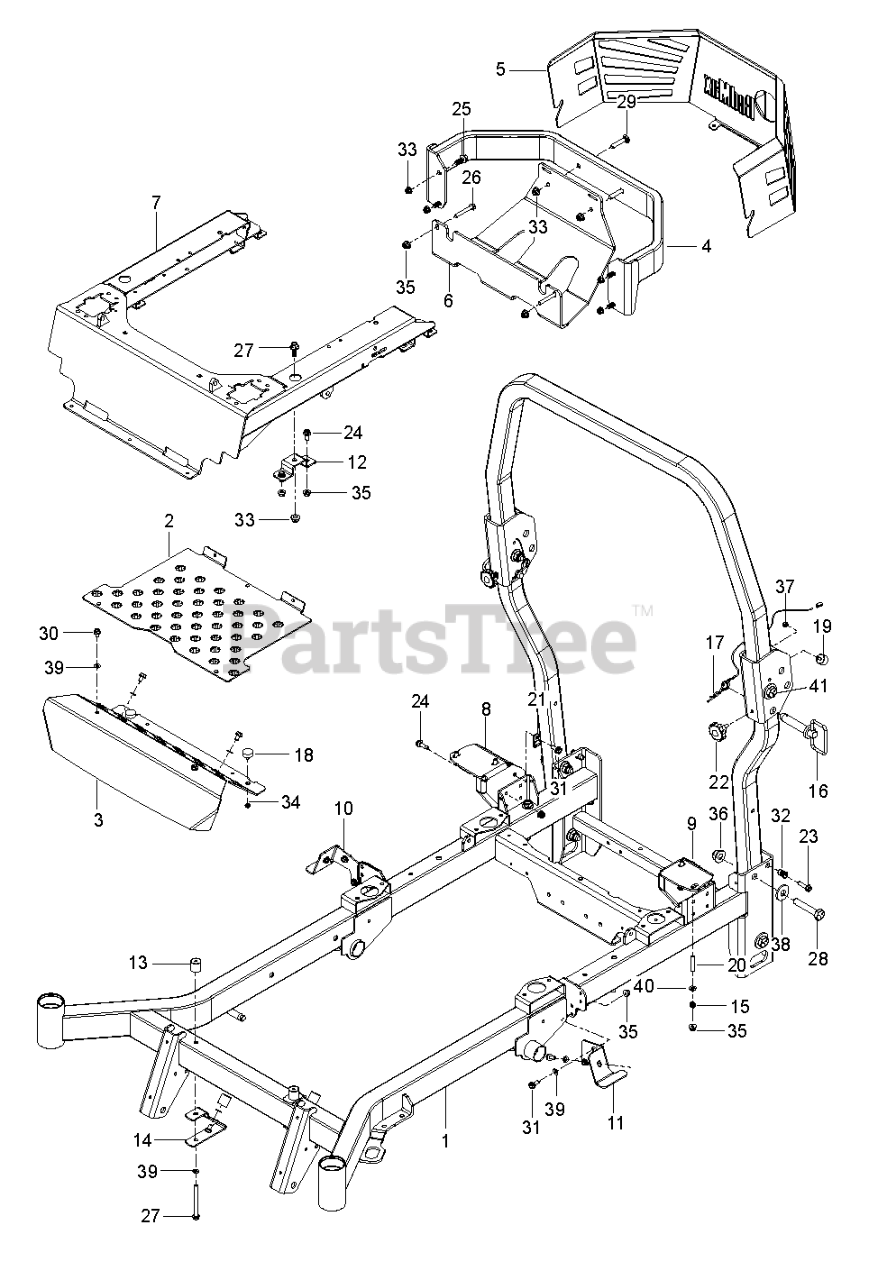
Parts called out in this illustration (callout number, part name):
1	FRAME.W/DECALS/CZT/REDMAX.672
2	PLATE FLOOR PAN SNAPPER RED X6
3	PLATE.FOOT.REST.BLACK
4	BUMPER REAR LONG SNAPPER RED X
5	GUARD REAR SNAPPER RED X672
6	PLATE, SKID, BLACK
7	FRAME SEAT MOUNT SNAPPER RED X
8	MOUNT, RT TANK, BLK
9	MOUNT, LT TANK, BLK
10	BRACKET TANK.FT.RT BLACK MS-43
11	MOUNT, TANK, LT-BLK
12	MOUNT MID-SECTION BLACK MS-431
13	MOUNT, F/F INSERT
14	BRACKET, REST MOUNT
16	PIN.ROPS.W/HANDLE
17	PIN.HAIR.DOUBLE.LOOP.W/LANYARD
18	BUMPER, 1/4-20 STUD, 1/4
19	BUMPER, MALE STUD, 1/4-20
20	STUD, 5/16C
21	DOUBLE TUBE CLAMP
22	KNOB.5/16-18X1"BLACK
23	HHFS 5/16-18 X 1.25 TPBLT GD 5
24	HHFS 5/16-18 X 3/4
25	HHFS 3/8-16 X 1 GRD 5 ZD
26	HHFS 5/16-18 X 2.25 GD 5
27	HHFS 5/16-18 X 3 3/4
28	5/8-11 X 3-1/2 HHB GRADE 5
29	RHSNB 3/8C X 2
30	SCR 5/16-18 X 1/2 SELFTAP ZN
31	SCREW
32	NUTSERT 5/16-18 THICK GRIP
33	NUT 3/8-16 HEX FLG NYLOC ZD
34	JAM NUT 1/4C (2 2 PW01)
35	5/16-18 NYLOC FLANGE NUT
36	NUT 5/8-11 FLG NYLOC ZD
37	RP_NUT 1/4-20 NYLOC
38	WASHER, 5/8 FLAT
39	WASH 5/16 DISC SPRING ZD
40	WASHER
41	BOLT.HEXAG.5/8-11X4-1/4.G5.ZPY
